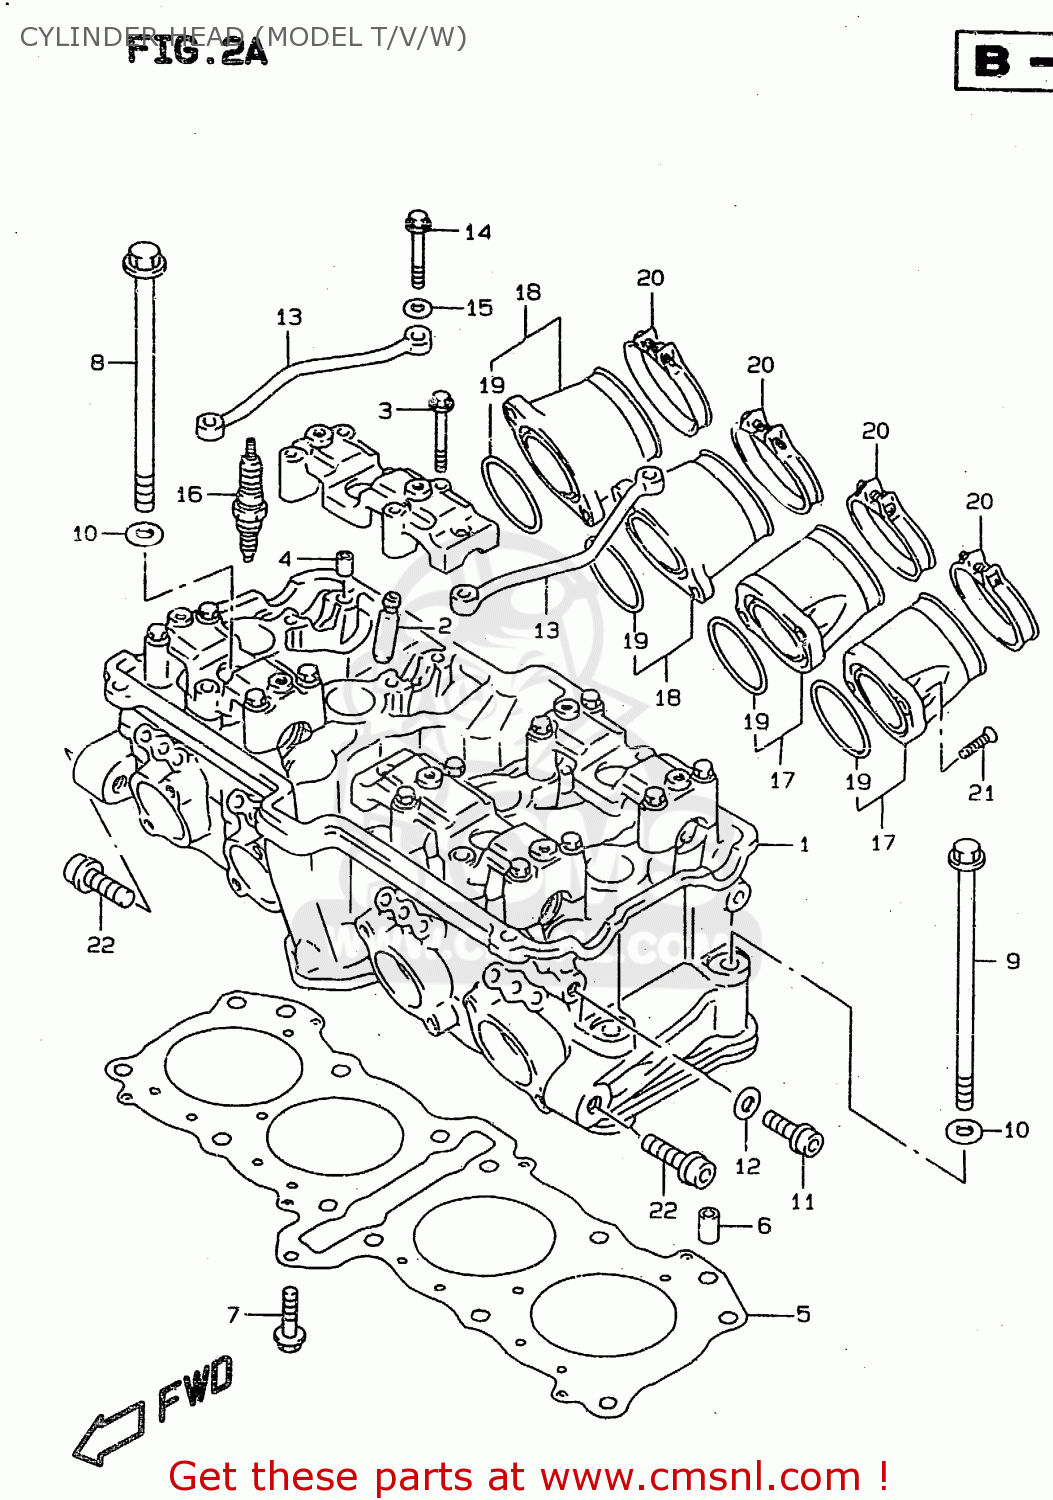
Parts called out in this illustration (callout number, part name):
1	HEAD ASSEMBLY,CYLINDER
2	GUIDE,VALVE
3	BOLT(6X45)
4	PIN(6.2X8X11)
5	GASKET,CYLINDER HEAD
6	PIN
7	BOLT
8	BOLT 10X175
9	BOLT(10X175)
10	WASHER(10.5X19X2)
11	BOLT
12	GASKET(8.2X14X1).6 (NAS)
13	PIPE,CYLINDER HEAD OIL
14	BOLT(6X39)
15	WASHER
16	PLUG,SPARK(CR8E)
17	PIPE, INTAKE NO. 1
18	PIPE, INTAKE NO. 2
19	O RING(D:2.4,ID:41.7)
20	CLAMP
21	SCREW
22	BOLT
